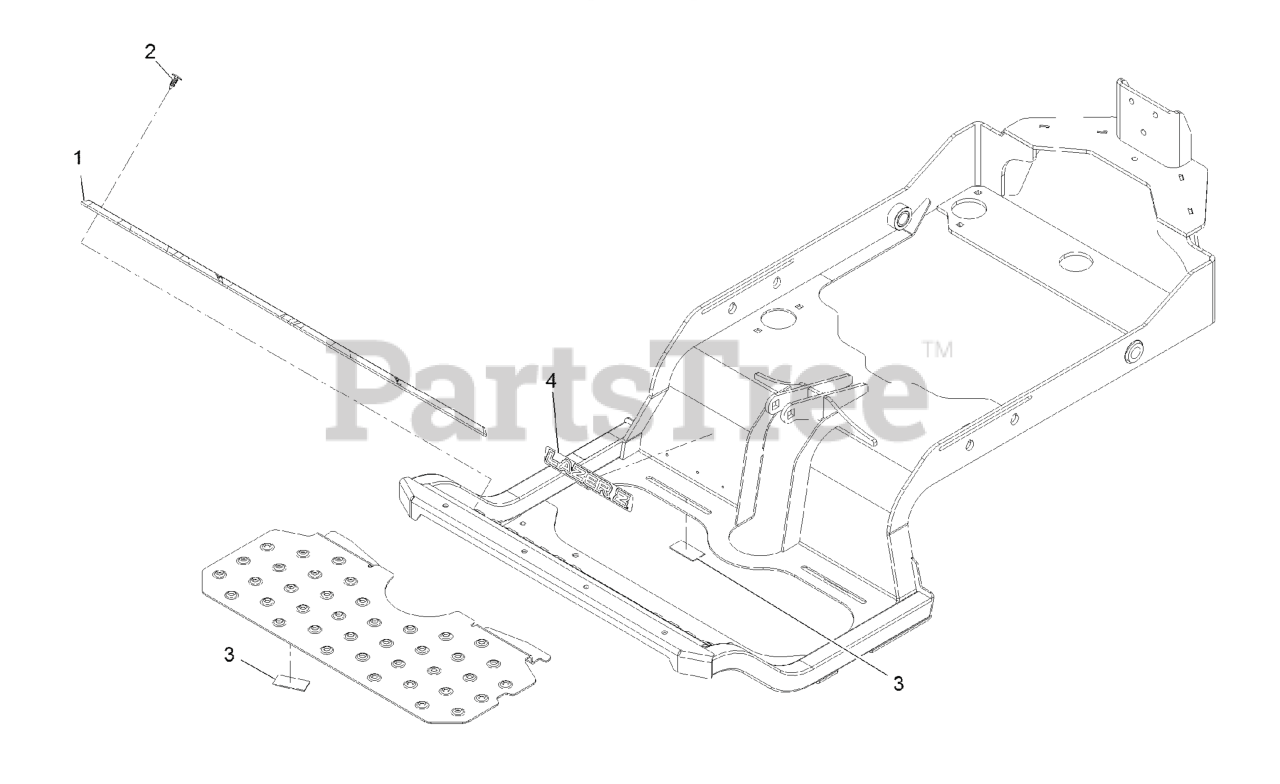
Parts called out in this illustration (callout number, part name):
1	FLOOR MAT
2	PLUG-PLASTIC
3	PAD-RUBBER
4	DECAL-LAZER LOGO
